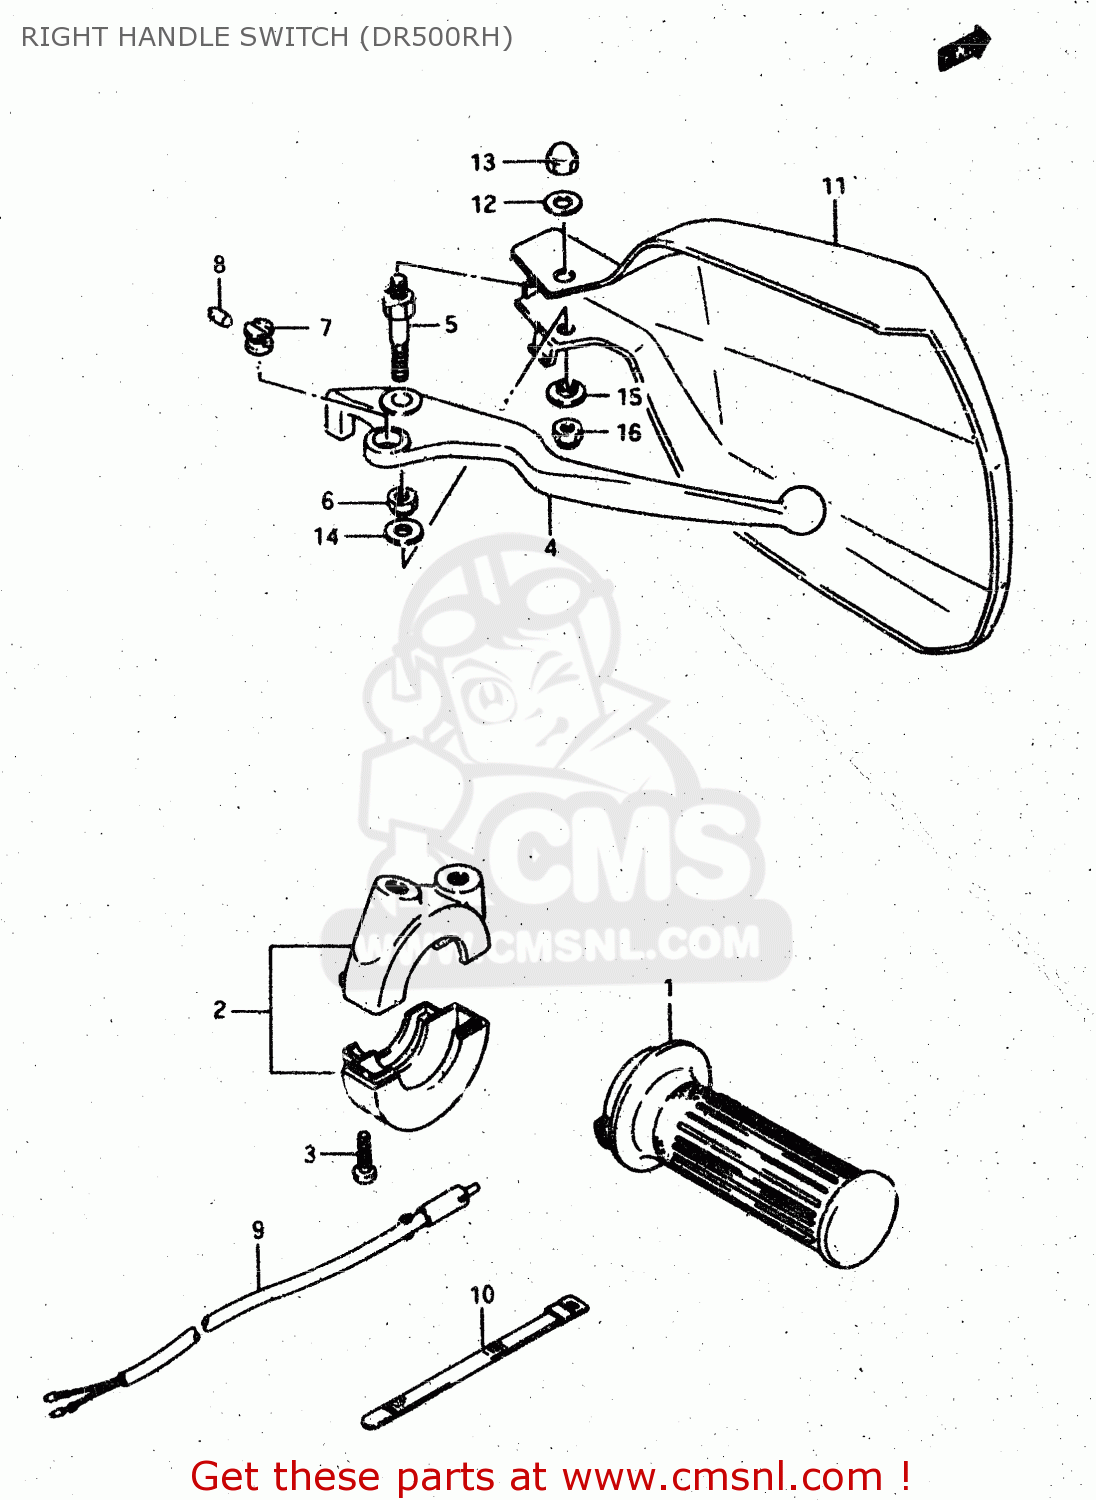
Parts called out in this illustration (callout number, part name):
1	GRIP,THROTTLE
2	CASE ASSY,THROTTLE
3	SCREW 5X20
4	LEVER,BRAKE
5	BOLT,BRAKE LEVER PIVOT
6	NUT
7	ADJUSTER
8	ROD,PUSH
9	SWITCH ASSY,STOP
10	CLAMP(L:120)
11	GUARD, KNUCKLE, RH (WHITE)
12	WASHER (6.5X20X1.6)
13	NUT 6MM
14	WASHER(6.5X16X1.2)
15	WASHER
16	NUT 6MM
